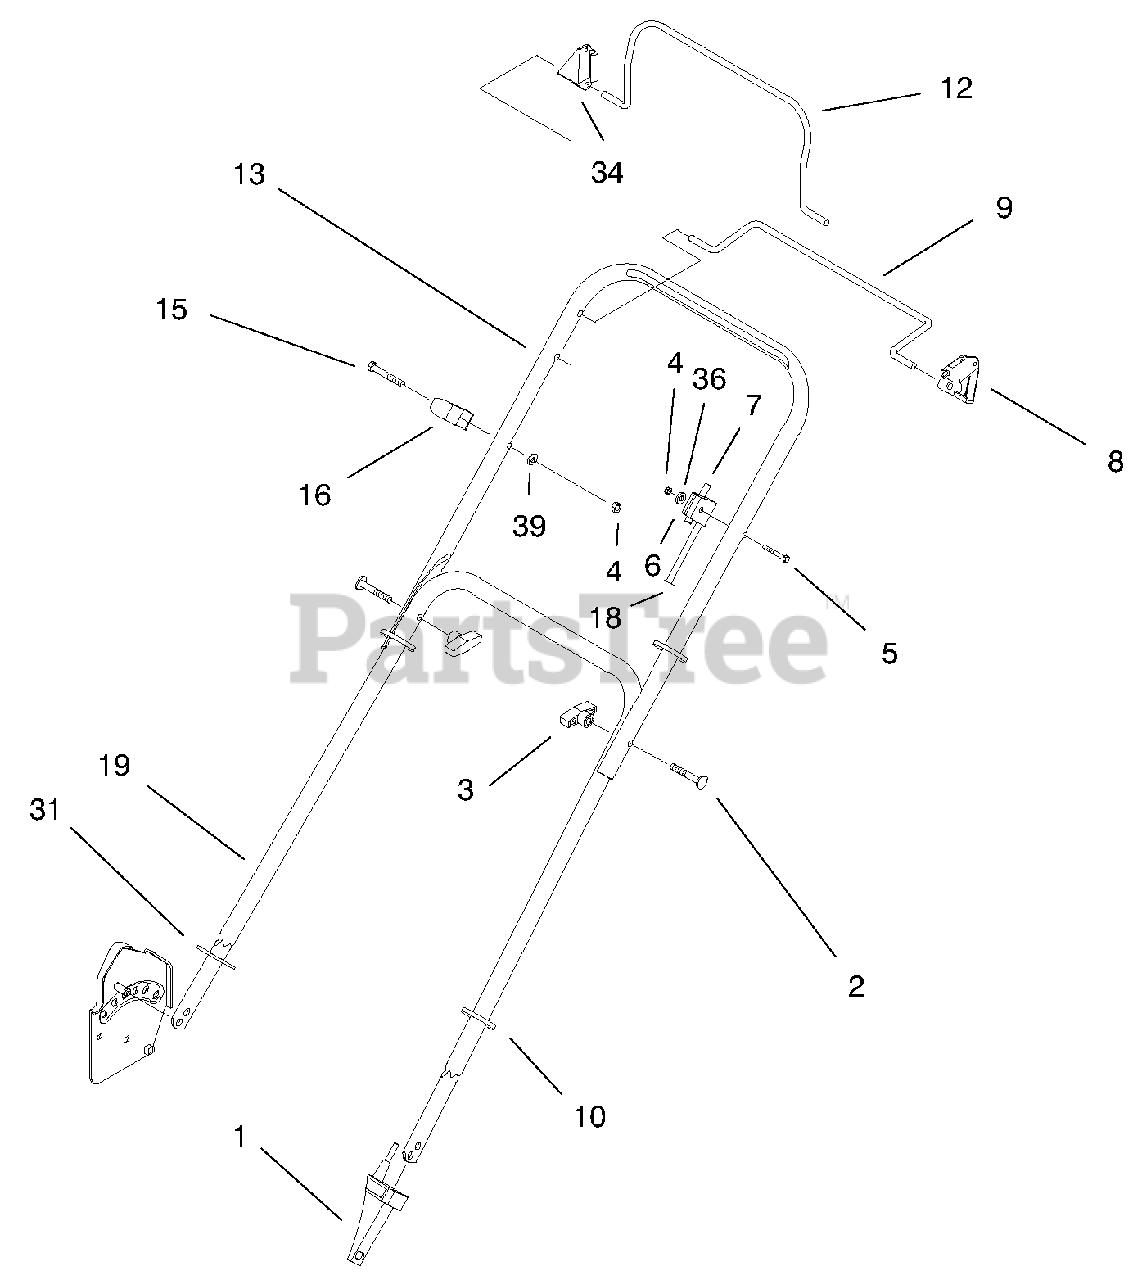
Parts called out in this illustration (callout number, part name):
1	Anchor-Cable
2	Screw-Handle
4	Nut-Lock
5	Screw-Handle
6	Anchor-Cable
7	Cable-Traction
8	Stop-Pivot
9	Bail-Sp Control
10	Tie Strap
12	Bail-Flywheel Brake
13	Handle Section-Upper
15	Bolt-Hex
16	Guide-Rope
18	ASM-Brake Cable
19	Handle Section-Lower
31	Handle-Guard
34	Stop-Bail
36	Washer-Flat
39	Washer
